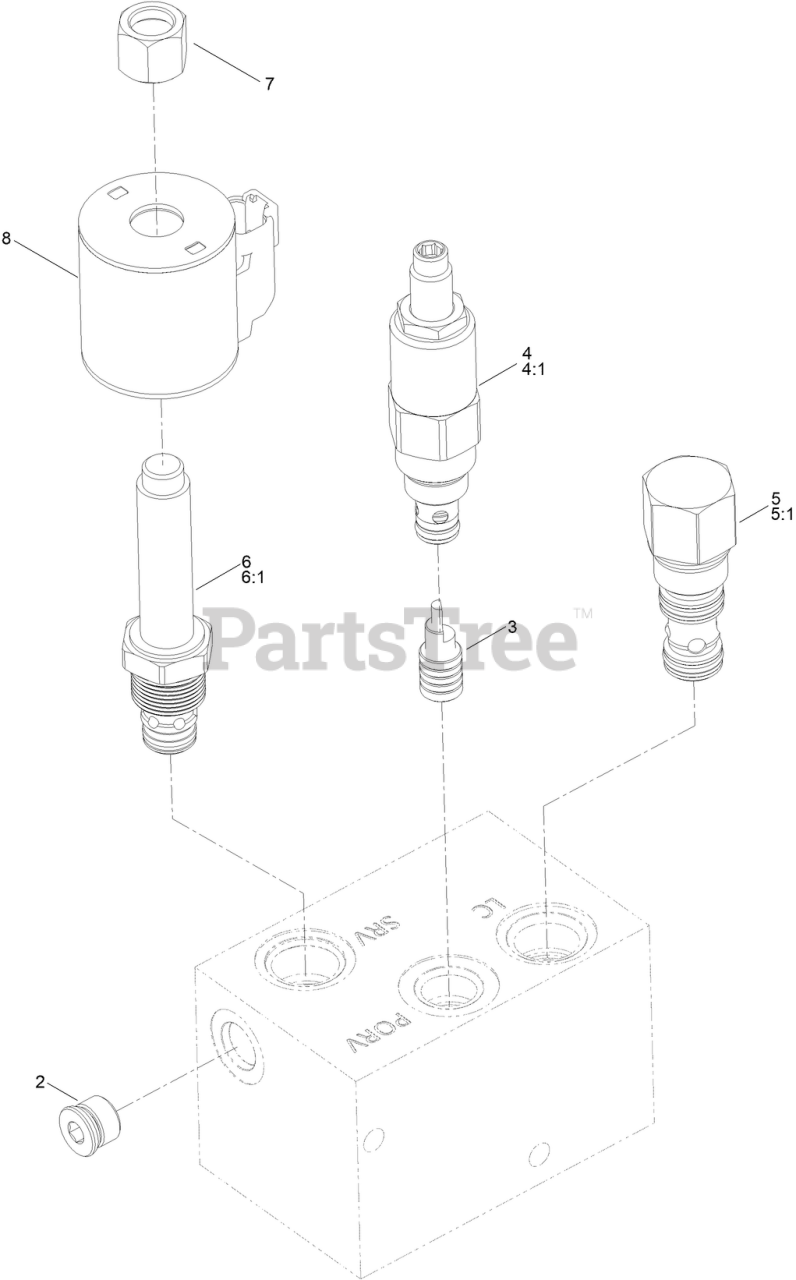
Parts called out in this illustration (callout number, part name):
3	PISTON-PILOT
4	VALVE-RELIEF
4:1	SEAL KIT
5	ELEMENT-LOGIC, VENTED
5:1	SEAL KIT
6	CARTRIDGE-RELIEF
6:1	SEAL KIT
7	NUT-COIL (9/16-24 UNEF-2B)
8	COIL-SOLENOID
